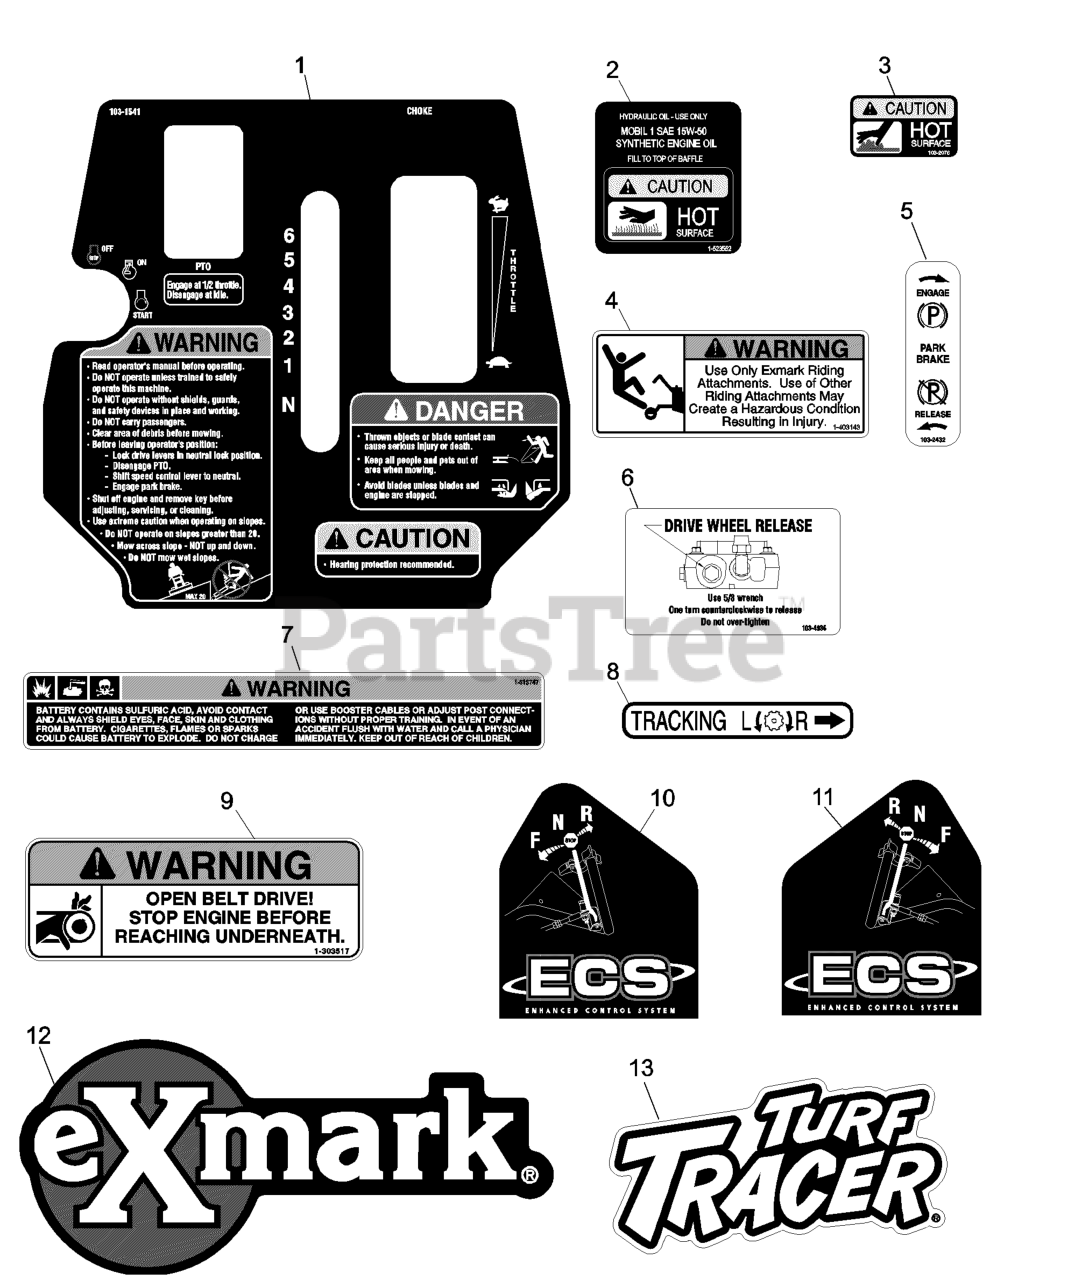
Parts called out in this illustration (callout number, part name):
1	DECAL,TTH ECS CONSOLE
3	DECAL-CAUTION
4	DECAL,SULKY WARNING
5	DECAL,PARKING BRAKE
6	DECAL,DRIVE RELEASE
7	DECAL-BATTERY
8	DECAL,TRACKING ADJUST
9	DECAL,BELT DRIVE
10	DECAL,LH ECS INSTRUCTION
11	DECAL,RH ECS INSTRUCTION
12	DECAL,EXMARK LOGO
13	DECAL,TTH MODEL
